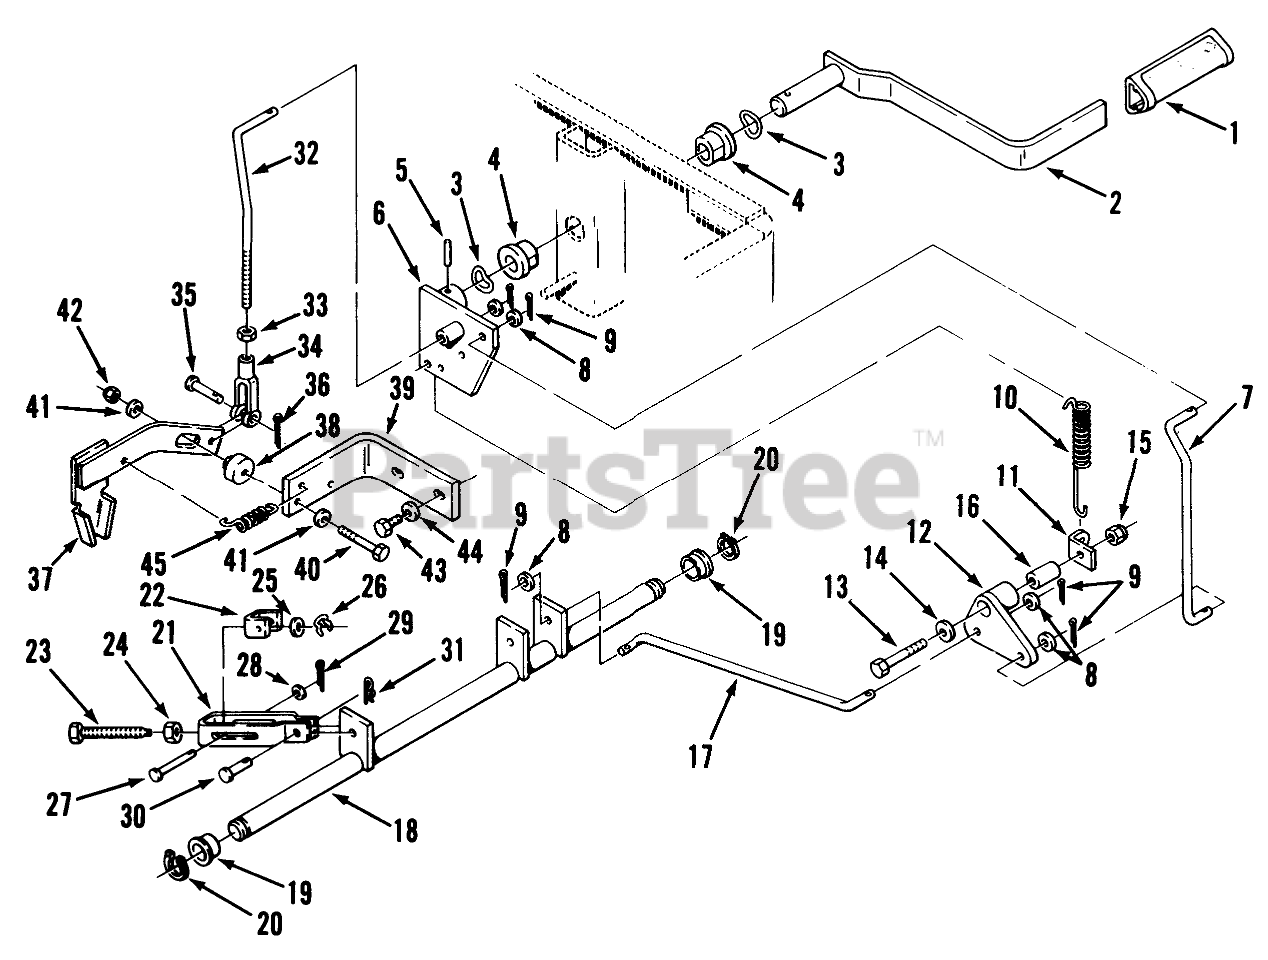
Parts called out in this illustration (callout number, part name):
1	GRIP-PARKING BRAKE
2	Brake Lever
3	WASHER-BOWED
4	BEARING-FLANGED
5	Roll Pin
6	Arm
7	ROD BRAKE UPPER
8	WASHER 5/16 SAE
9	Cotter Pin
10	SPRING-EXTENSION
11	CLIP - SPRING
12	WLMNT-BRAKE PIVOT
13	Bolt
14	Washer
15	NUT
16	SPACER
17	ROD BRAKE LOWER
18	WLMNT-BRAKE SHAFT R
19	BUSHING
20	RING-SNAP, EXTERNAL
21	WLMT BRAKE YOKE A R
22	YOKE-BRAKE ADJUST R
23	BOLT-ADJUSTER
24	Nut
25	WASHER
26	CLIP-RING 1/4"
29	Cotter Pin 1/16 x 3/4
30	Clevis Pin 5/16 x 5/8
31	Hairpin
32	ROD-NEUTRAL LOCK
33	Nut
34	CLEVIS
36	Cotter Pin
37	Lock-Neutral
38	SPACER
39	Bracket-Support
40	Screw-Hex. Hd.
41	WASHER
42	Nut
43	Screw
44	WASHER 5/16 SAE
45	SPRING-EXTENSION
